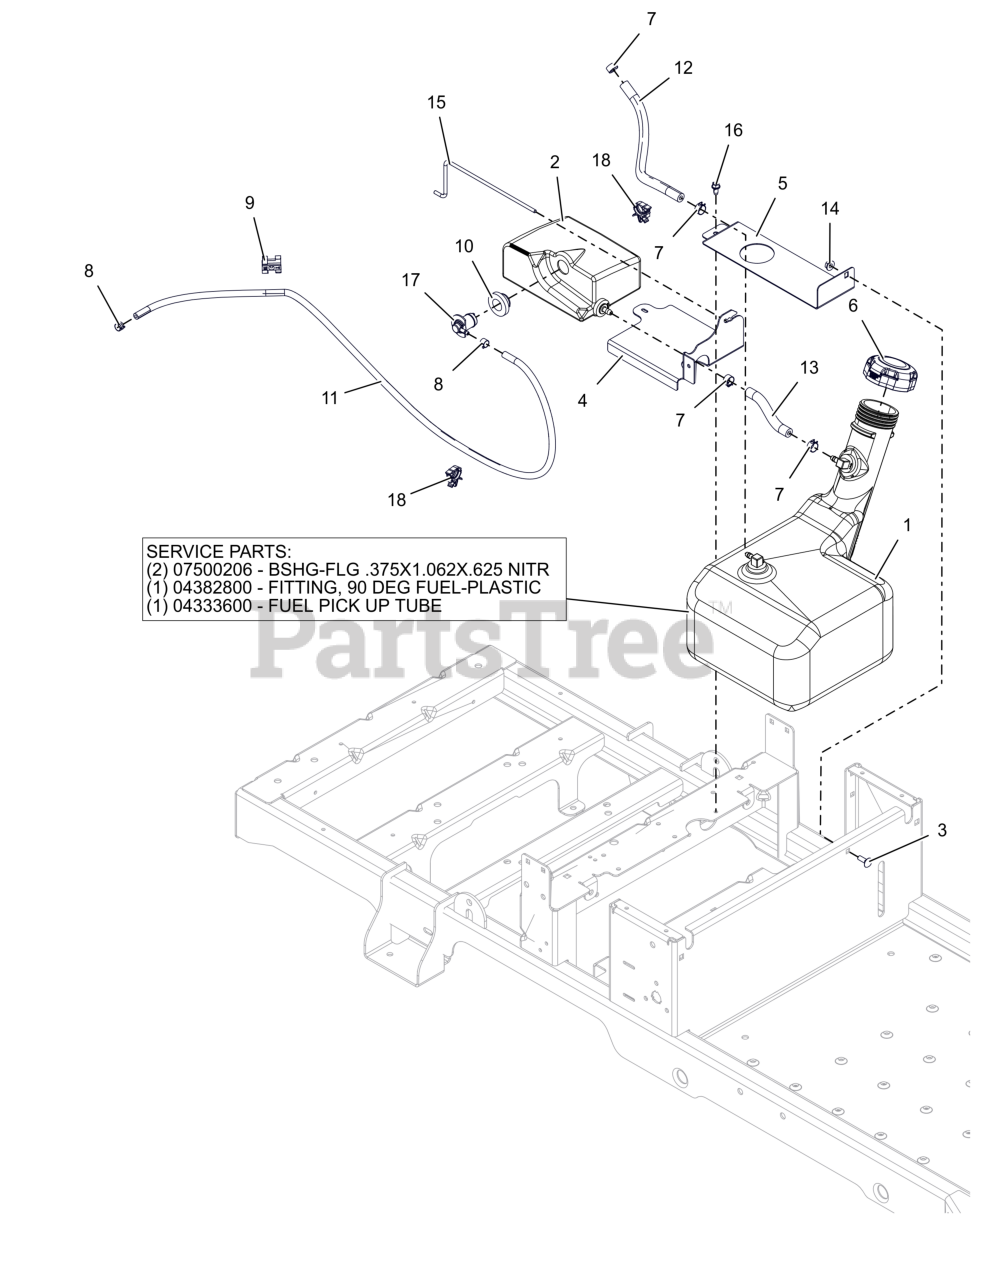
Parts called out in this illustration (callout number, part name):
1	ASM, FUEL TANK
2	ASM, FUEL TANK - EXPANSION
3	BLT, RHSN .25-20X.750 G5 ZCC
4	BRKT, EXPANSION TANK (RED)
5	BRKT, TANK STRAP
6	CAP-FUEL- 2.25 RATCHET INLET V
7	CLAMP, FUEL LINE
8	CLAMP-HOSE, SPRING .188
9	CLIP, T, .38-.50
10	GROMMET, REMOTE VENT NITRILE
11	HOSE, .188 LOW-PERM BULK GAS
12	1 INCH OF HOSE, .25 LOW-PERM BULK GAS
13	1 INCH OF HOSE, .25 LOW-PERM BULK GAS
14	NUT-LK-CTR-FLG .25-20 ZC120
15	ROD, HOLDDOWN (BLACK)
16	SCR-TAP .25-20X.50 HWH ZCC
17	VALVE, 2-WAY
18	WIRE CLIP
